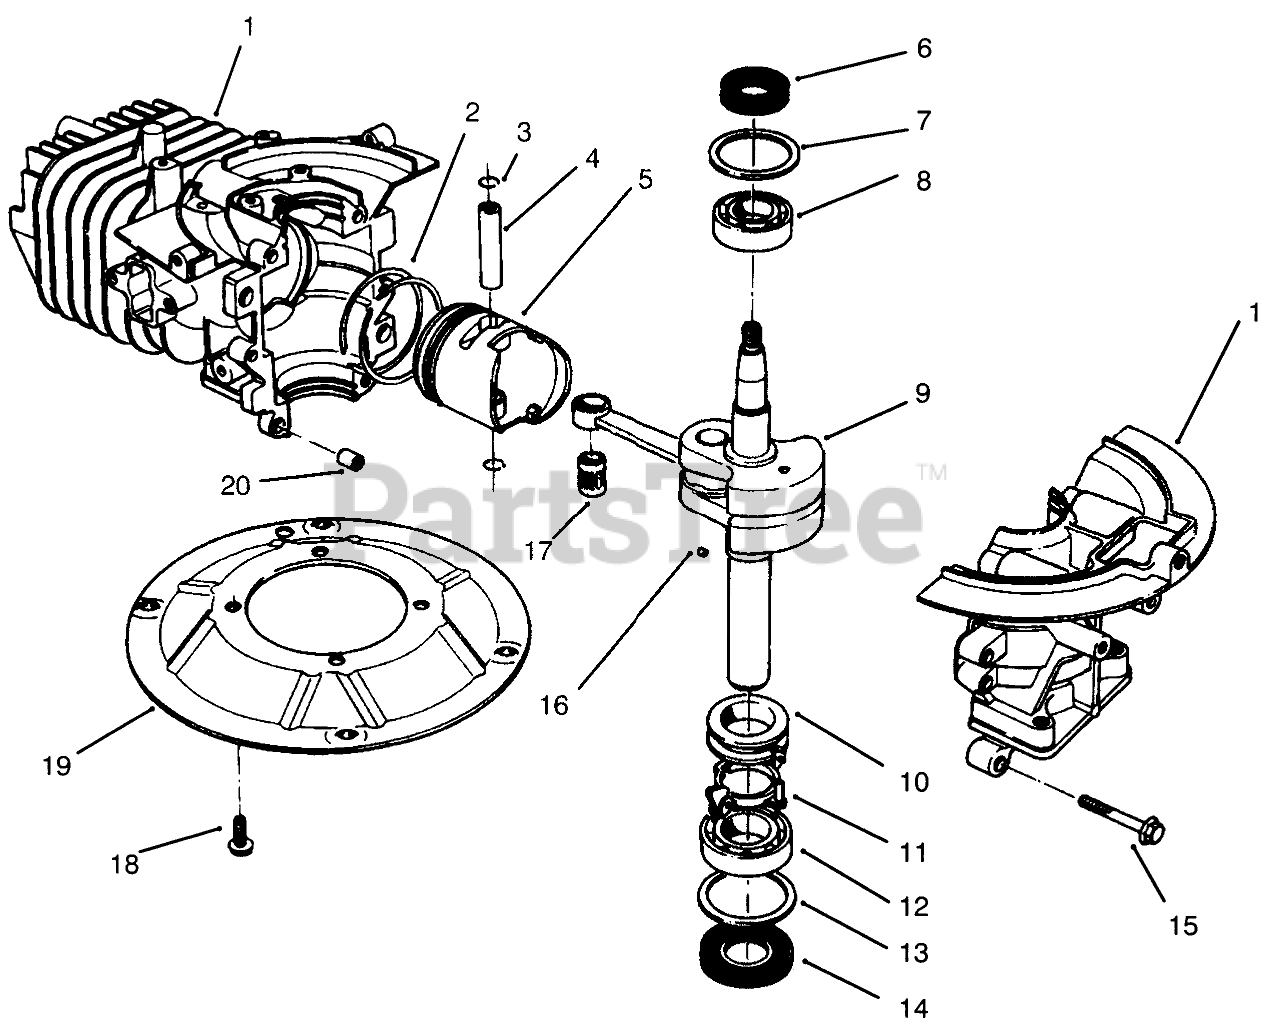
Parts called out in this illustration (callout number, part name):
1	CRANKCASE
2	RING SET
4	PIN-PISTON
5	PISTON
6	OIL SEAL
7	WASHER-UPPER
8	BEARING-UPPER
9	Crankshaft/Connecting Rod Assembly
10	SPACER
11	BRACKET
12	LOWER BRG
13	WASHER-LOWER
14	SEAL-OIL
17	BEARING
19	PLATE-MOUNTING
